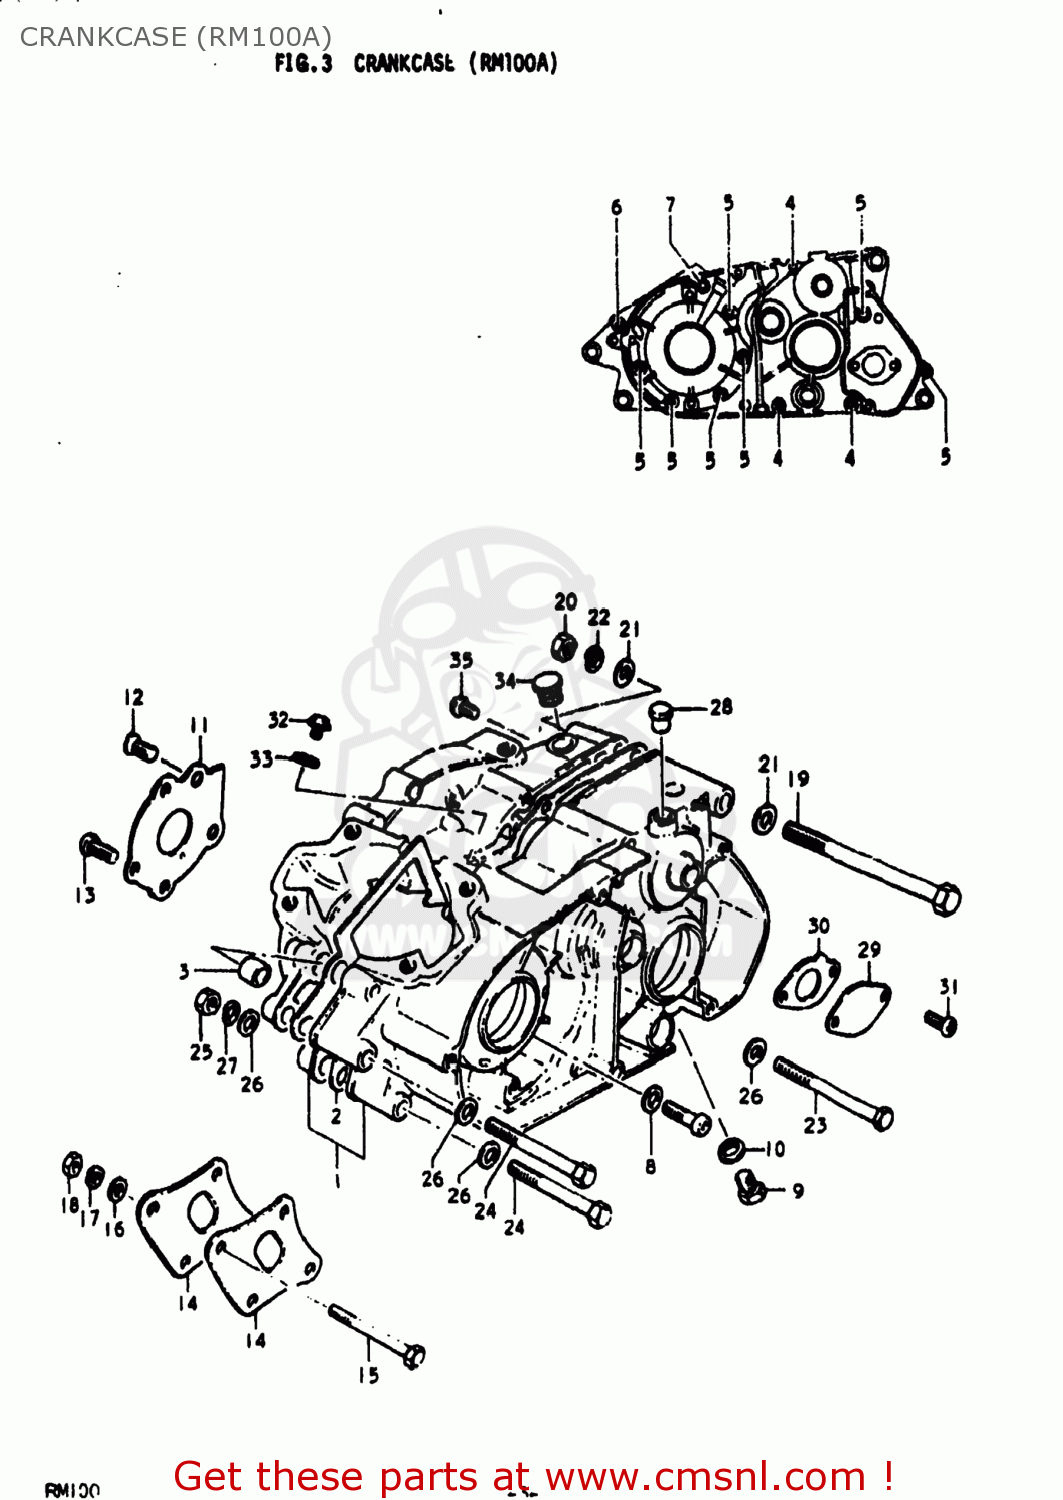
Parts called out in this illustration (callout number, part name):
1	CRANKCASE SET
2	GASKET,CRANKCASE (MCA)
3	PIN
4	SCREW
5	SCREW (6X45)
6	SCREW 6X80
7	SCREW 6X60
8	WASHER 6MM
9	PLUG
10	GASKET(10X14X3.6) (NAS)
11	PLATE,OIL RESERVOIR
12	SCREW
13	SCREW
14	PLATE,ENGINE MOUNTING
15	BOLT
16	WASHER
17	LOCK WASHER
18	NUT
19	BOLT
20	NUT
21	WASHER
22	LOCK WASHER
23	HEXAGON BOLT 8X80
24	BOLT
25	NUT
26	WASHER
27	LOCK WASHER
28	CAP(OD:14)
29	CAP,OIL PUMP DRIVE SHAFT
30	GASKET,OIL PUMP (MCA)
31	Screw
32	BOLT
33	GASKET(6.2X11X1).2 (NAS)
34	Plug
35	SCREW,6X6
